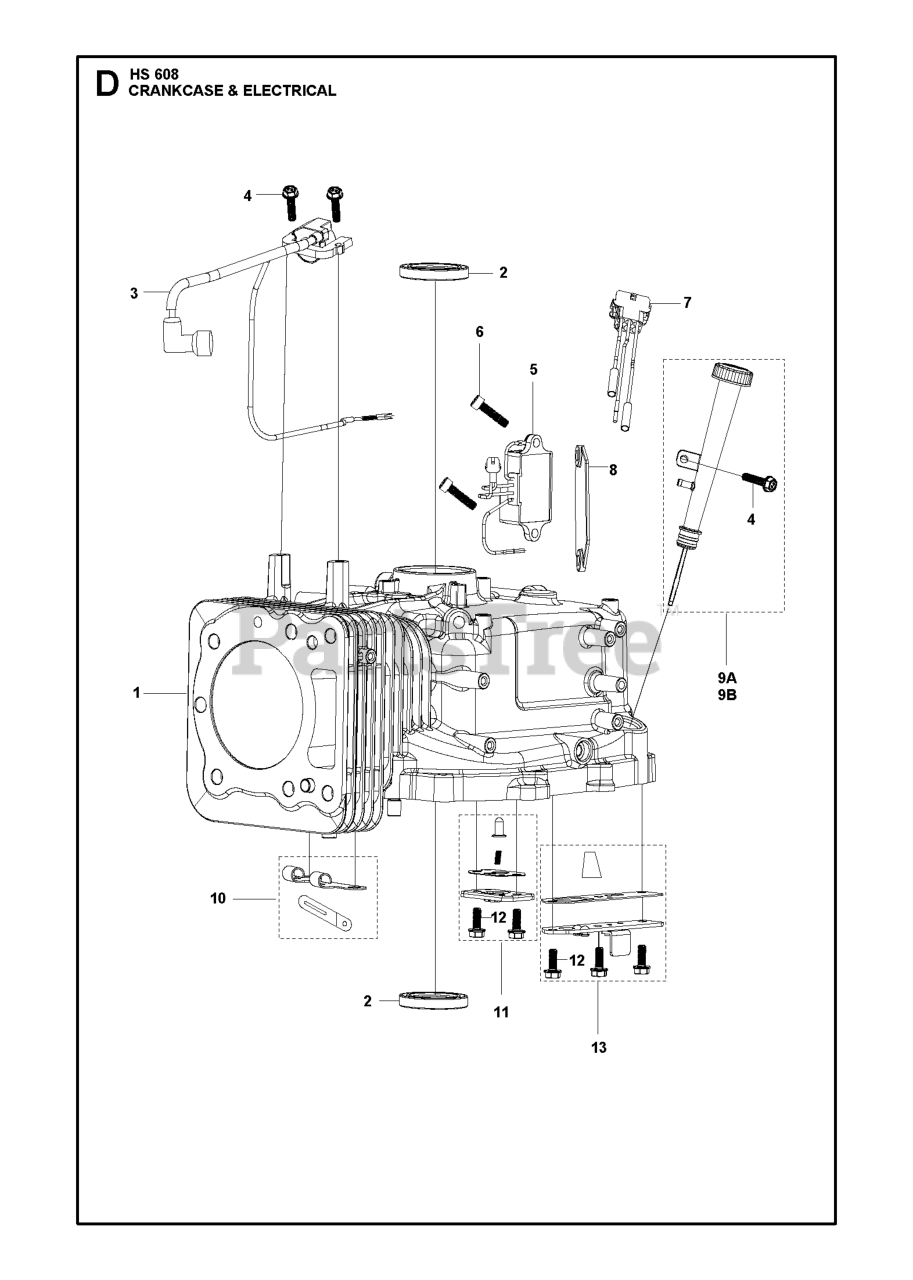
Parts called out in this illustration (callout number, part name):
2	SEAL OIL SEAL
3	IGNITION COIL
4	BOLT GB/T 5789: M6 L=20
5	VARIATOR.VOLTAGE RECTIFIER KIT
6	BOLT GB/T 70.1: M6 L=20
7	CONNECTOR CONNECTING WIRE
8	GASKET INSULATION GASKET
9A	DIPSTICK.
9B	DIPSTICK
10	CABLE GUARD KIT
11	REGULATOR REGULATOR VALVE AND
12	Husqvarna TBD
13	VALVE KIT LEAF VALVE
